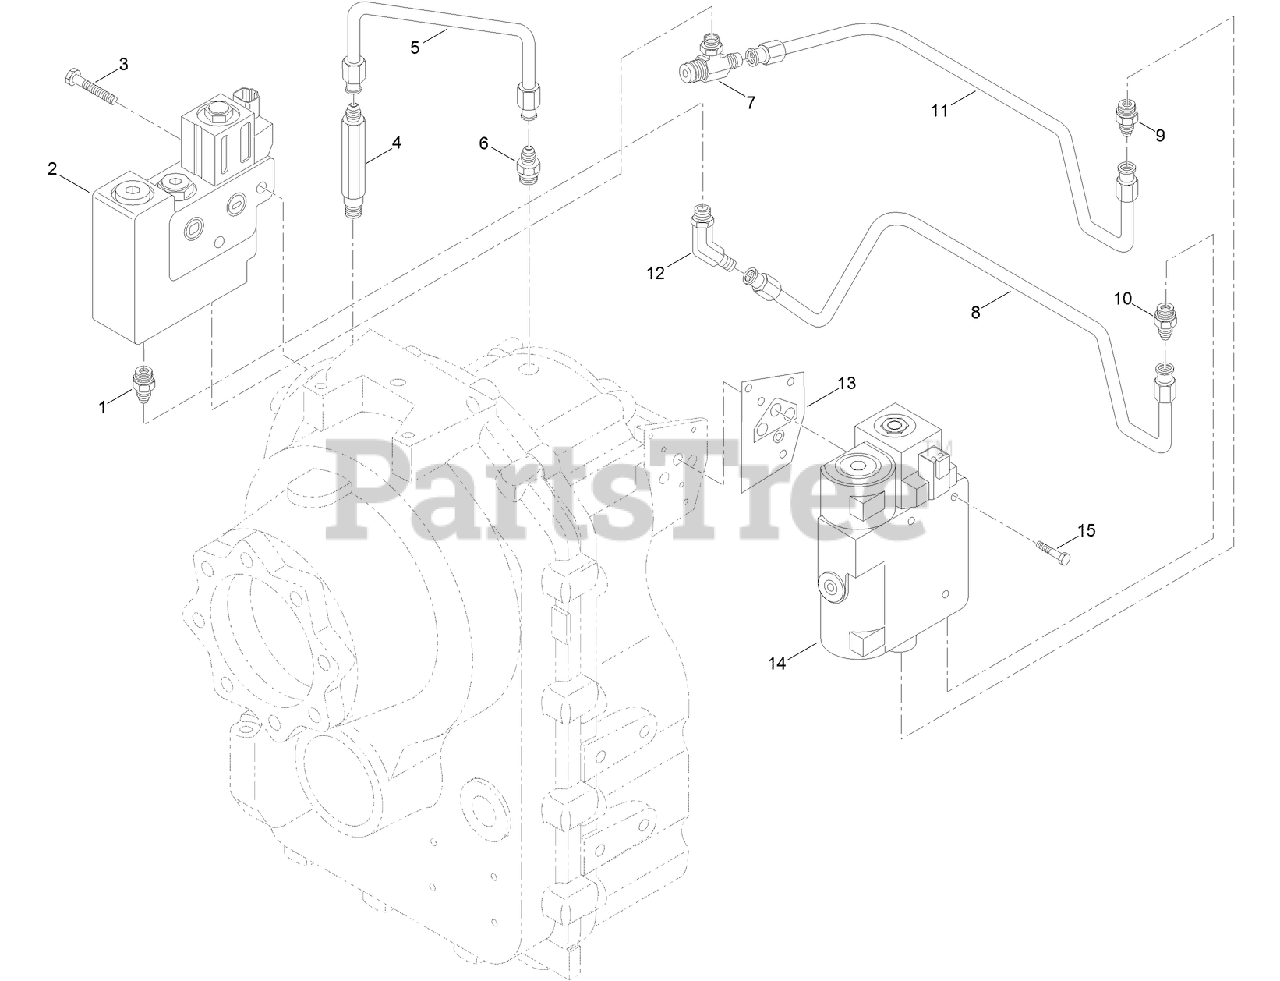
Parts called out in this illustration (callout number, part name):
1	FITTING-PIPE
2	VALVE-CONTROL, BRAKE
4	FITTING-NF
6	CONNECTOR
7	FITTING-NF
9	FITTING-NF
10	CONNECTOR
12	FITTING-PIPE
13	GASKET-VALVE, CONTROL
14	VALVE-CONTROL, CLUTCH
